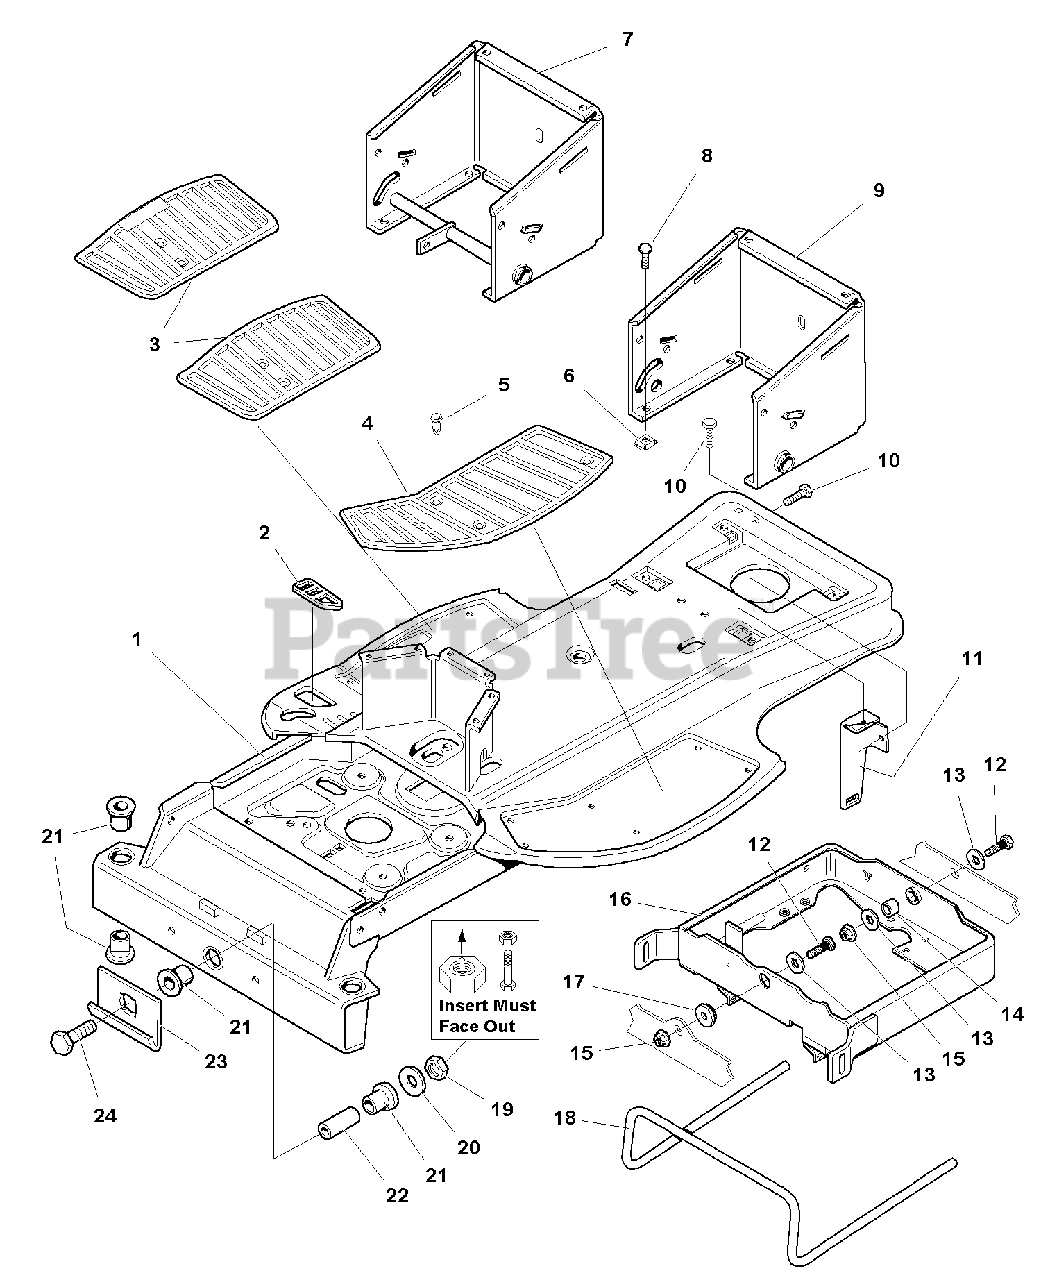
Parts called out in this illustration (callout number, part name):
1	FRAME ASSEMBLY
3	PAD, Footrest RH, (Hydro Only)
3	PAD, Footrest RH, (Gear Only)
4	PAD, Footrest LH
5	FASTENER, Panel
6	NUT, Speed 5/16-18
7	WRAPPER ASSEMBLY, Gear
8	SCREW, Hex Head Flange Lock, 5/16-18 x 3/4 (Gear Only)
9	WRAPPER ASSEMBLY, Hydro
10	CAPSCREW, Hex Head Flange Whiz Lock, 5/16-18 x 3/4 (Hydro Only)
11	BRACKET, (Gear Only)
12	CAPSCREW, Hex Head, 1/2-13 x 1/2
13	WASHER
15	NUT, Hex Head, 1/2-13
16	CARRIER ASSEMBLY, Hydro
16	CARRIER ASSEMBLY, Gear
18	BAR, Torsion, Hydro
18	BAR, Torsion, Gear
19	NUT, Hex Head ALUM Insert, 3/8-16
20	WASHER
23	"J" HOOK, Hitch
24	CAPSCREW, Hex Head, 3/8-16 x 3, G8
